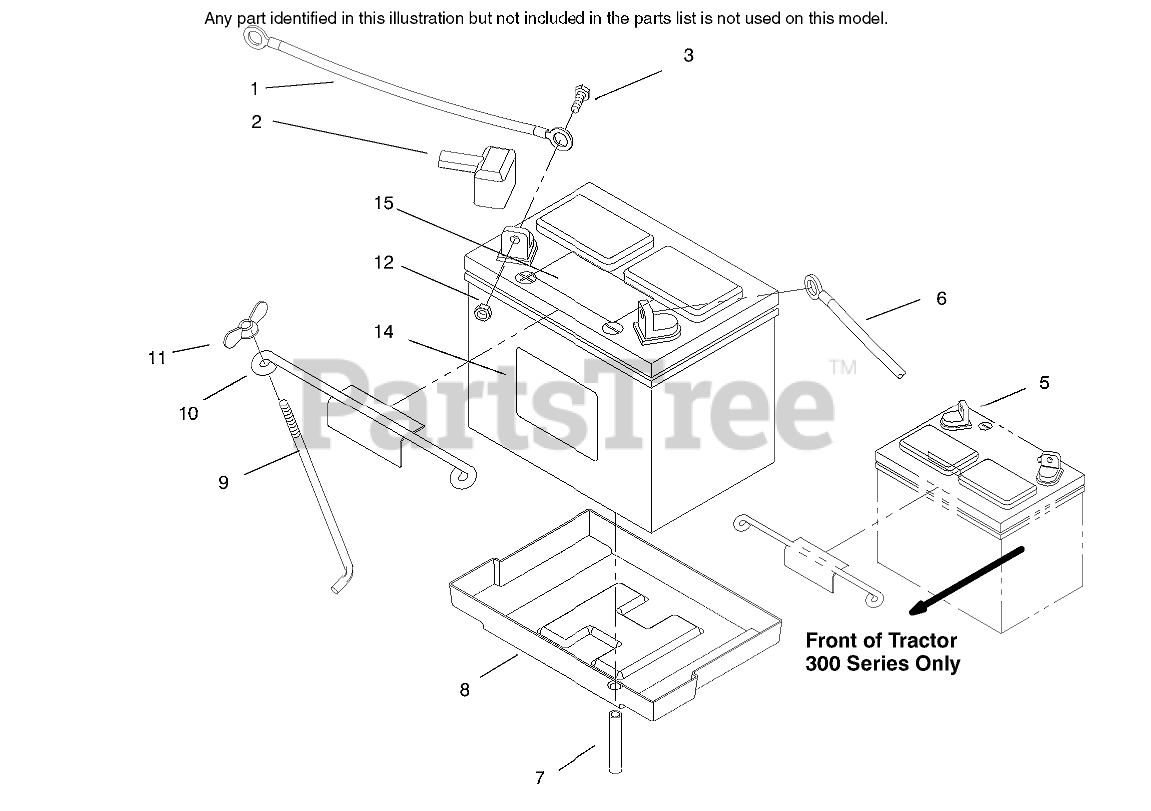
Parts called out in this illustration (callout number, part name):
1	CABLE-BLACK
2	BOOT-TERMINAL
3	SCREW-HH
5	Battery
6	ASSY WIRE
7	TUBE-21" BATTERY DRAIN
8	TRAY-BATTERY
9	HOOK-BATTERY RETAIN
10	HOLDDOWN-BATTERY
11	NUT-WING
12	NUT-LOCK, NI
